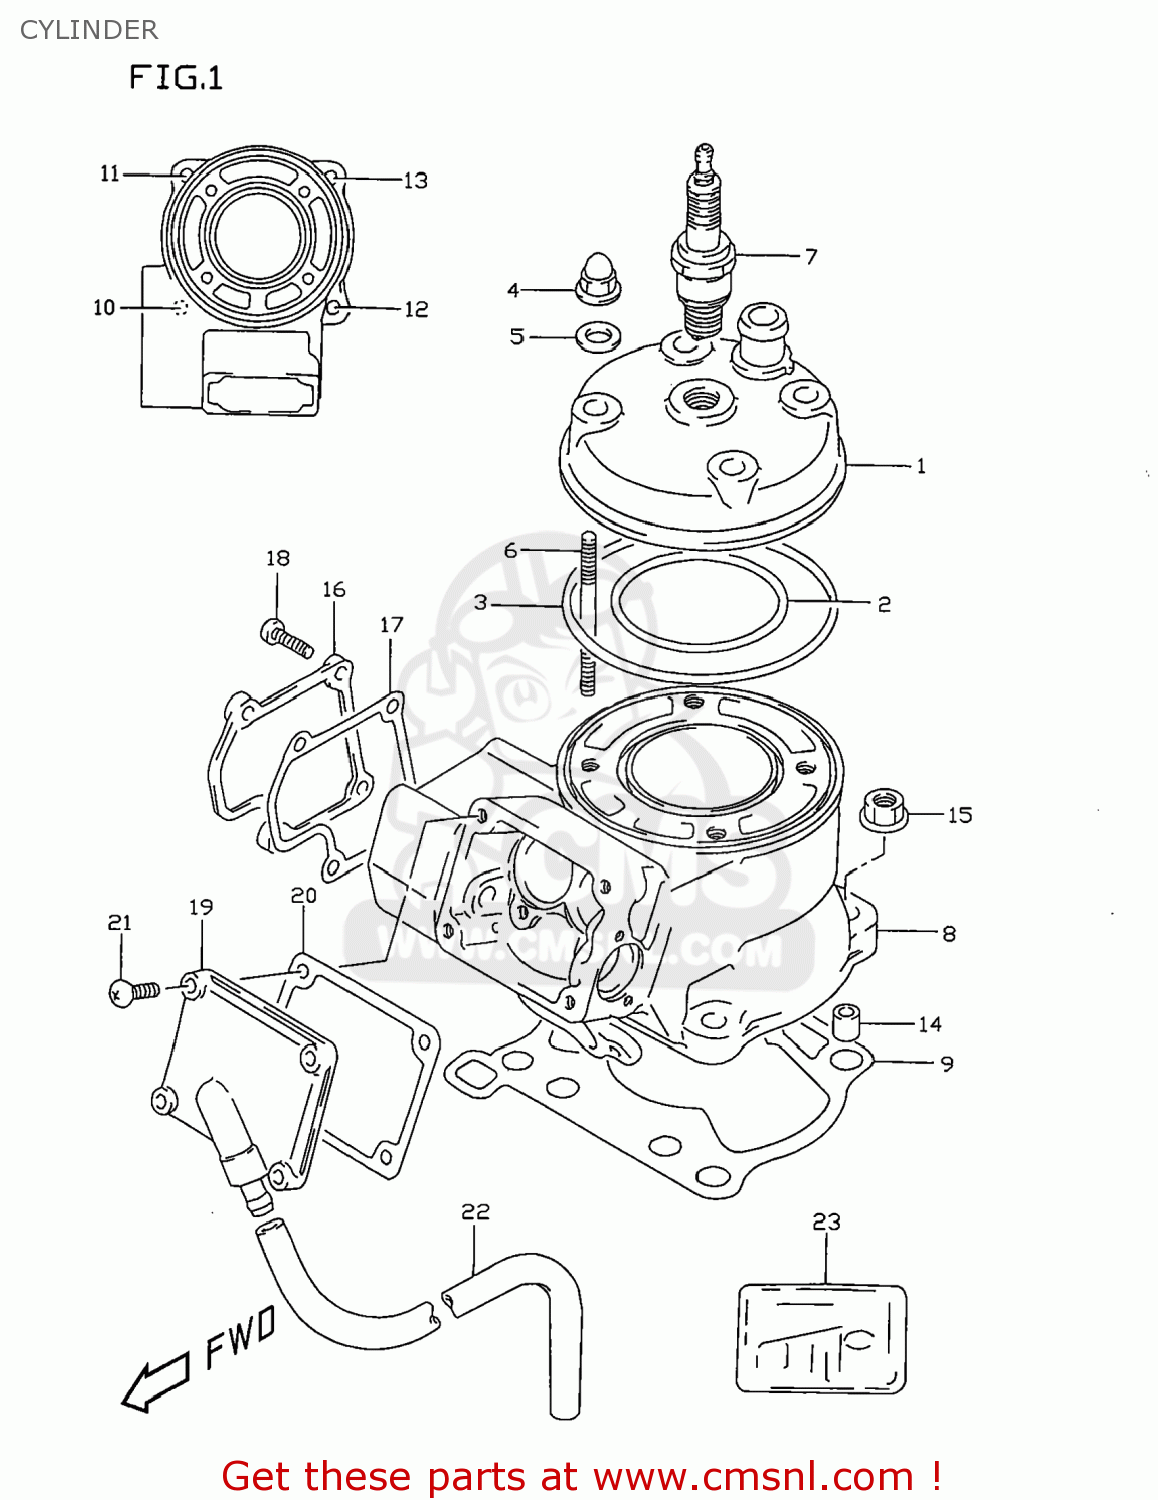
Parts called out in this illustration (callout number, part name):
1	HEAD,CYLINDER
2	O RING,CYLINDER HEAD NO.1
3	O RING,CYLINDER HEAD NO.2
4	NUT
5	GASKET(8.5X17X2.3) (NAS)
6	BOLT,STUD
7	PLUG,SPARK(BR10ES)
8	CYLINDER COMP
9	GASKET,CYLINDER (NAS)
10	BOLT,STUD
11	STUD 8X25
12	BOLT,STUD
13	BOLT,STUD
14	PIN(8.4X11X14)
15	NUT
16	COVER,CYLINDER NO.1
17	GASKET,CYLINDER COVER NO.1 (NAS)
18	SCREW
19	COVER,CYLINDER
20	GASKET,CYL COVER NO.2 (NAS)
21	SCREW
22	HOSE(7X12X600)
23	GASKET SET (NAS)
